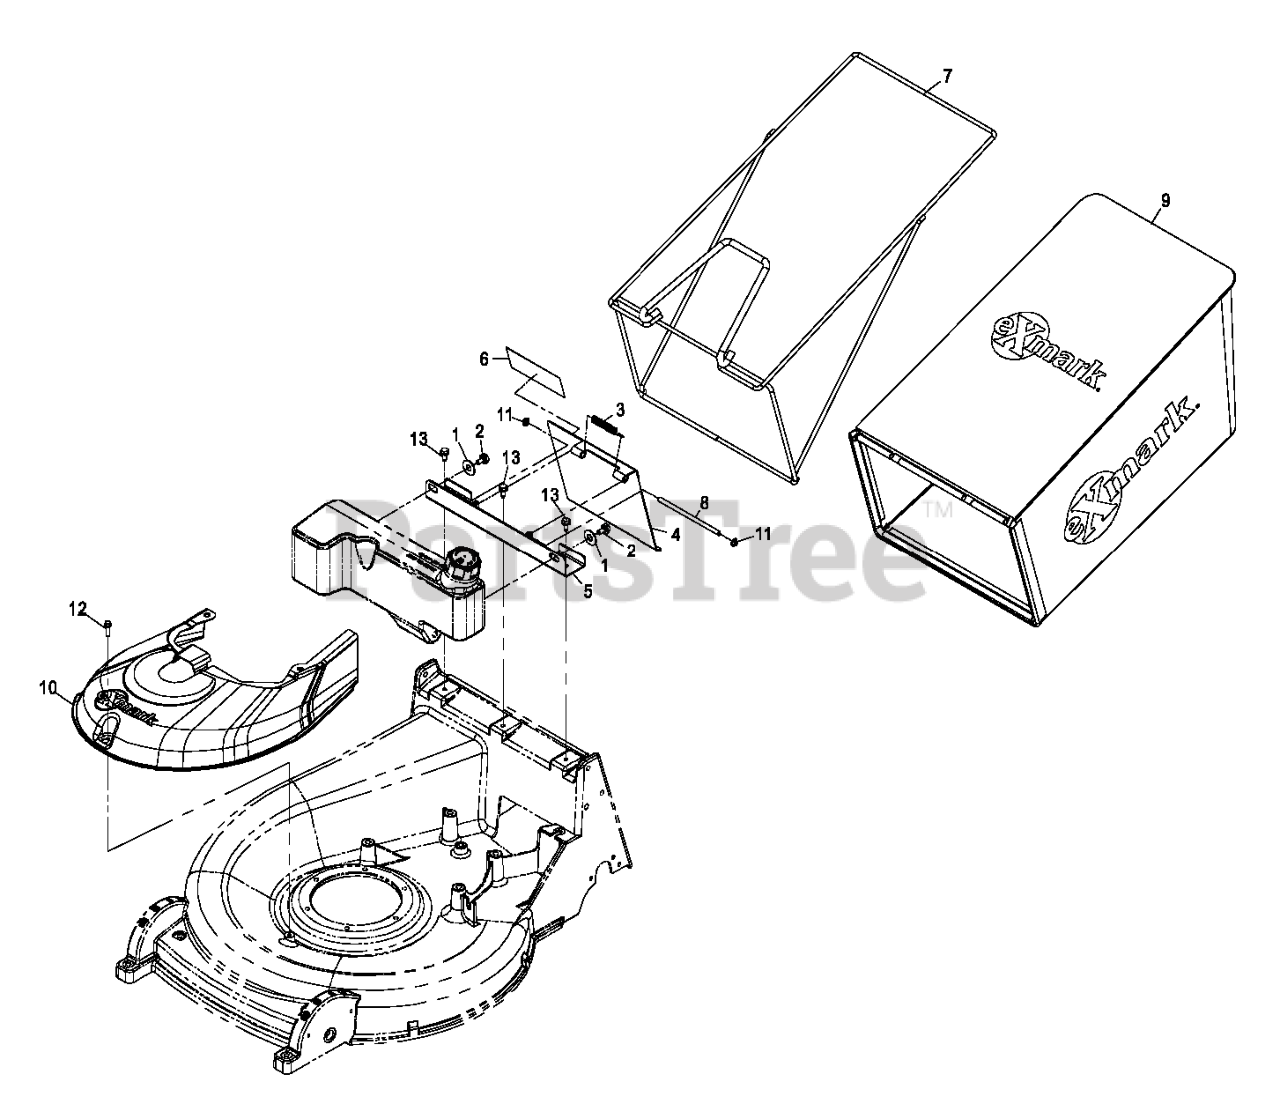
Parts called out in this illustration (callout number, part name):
1	WASHER-PLASTIC
2	BOLT-SHOULDER,HFH
3	SPRING-TORSION
4	ASM,DOOR W/DECALS METRO 2
5	BRACKET-MOUNT, BAG/DOOR
6	DECAL-WARNING
7	FRAME-BAG
8	ROD-PIVOT, DOOR
9	BAG,METRO 26 3.0 BU
10	COVER,SPINDLE
11	NUT-PUSH
12	SCREW-HWHTF
13	Screw-HWH 5/16-18 X 3/4 Tf
